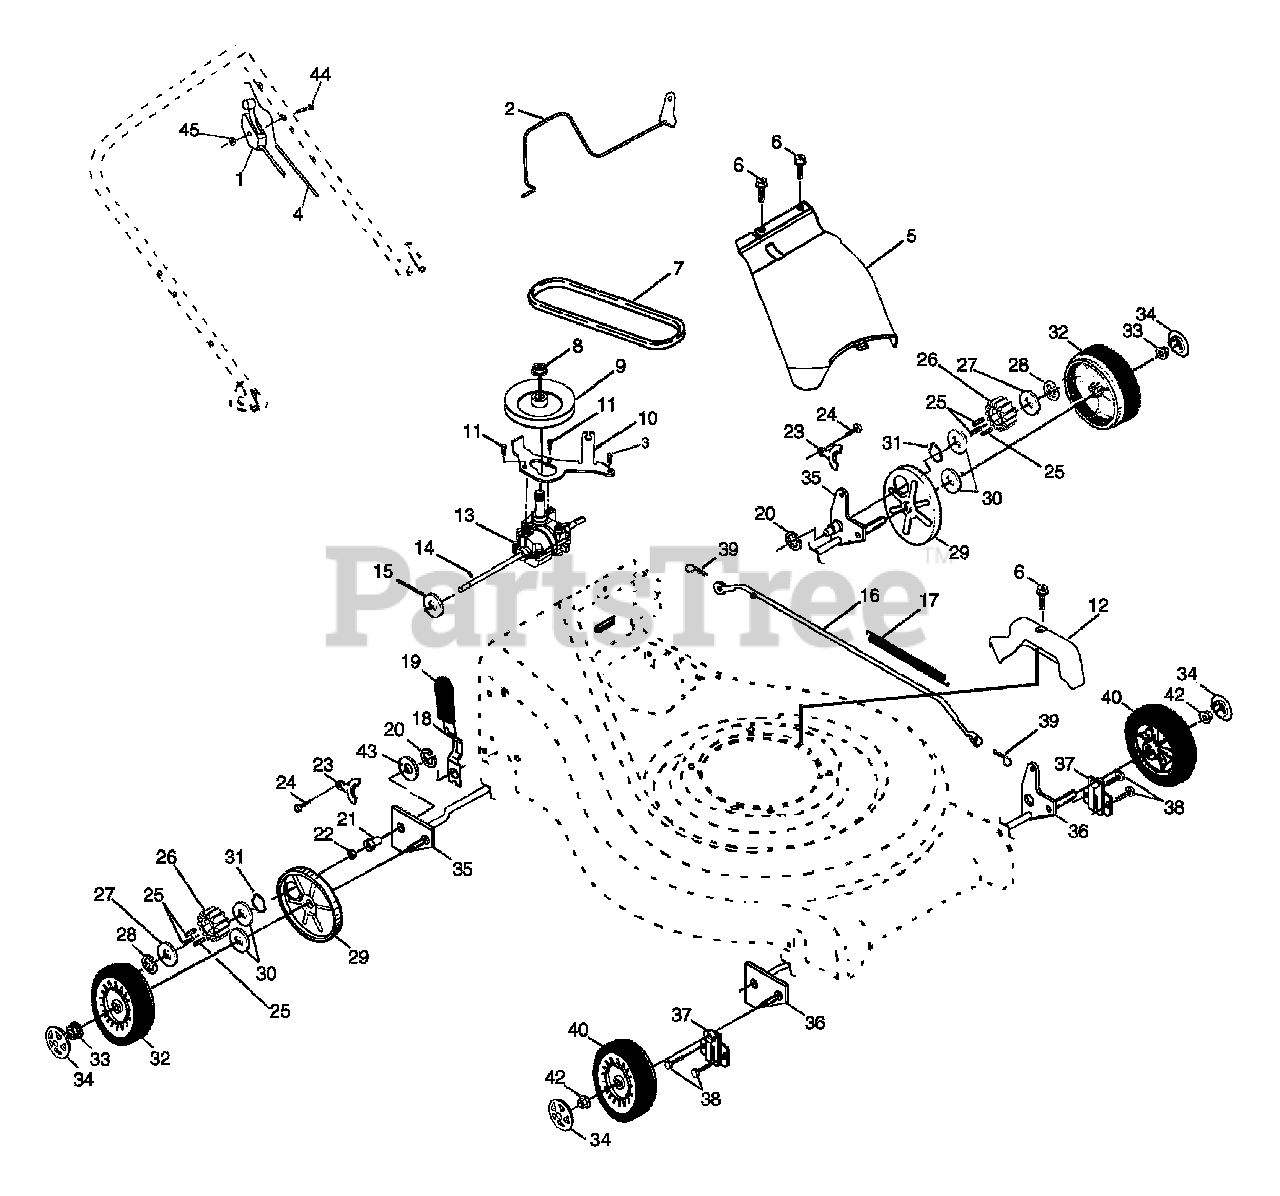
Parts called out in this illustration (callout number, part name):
1	Speed Control
2	Bail Control Drive
4	Drive Cable
5	Cover Drive
6	Screw Thdrol 10-25 x .50
8	Nut Lock Flanged 3/8-16 Zinc
9	Pulley Driven
10	Belt Keeper Bracket
11	Screw Hex Wash Head 10-24 X .668
12	Pivot Rod Cover
13	Transmission Asm.
14	Pin Spring Thrust
15	Washer Hardened
16	Rod Connecting
17	Spring Extension
18	Spring Selector
19	Knob Selector Spring
20	E-Ring 7/8
21	Bearing Support
22	Bearing Ball
23	Retainer Drive Asm. Stmp.
24	Screw Hex Head Tapping 1/4-20 x .75
25	Drive Pawl
26	Pinion, Drive
28	E-Ring 7/16
29	Cover, Dust Wheel
30	Washer 1/2 x 1-1/2 x .134
31	Wave Washer
32	Wheel 9 x 2
33	Nut Hex Flange Lock
35	Shaft Asm. Rear
36	Shaft Asm. Front
37	Retainer Front Shaft
38	Screw 12 x 5/8
39	Clip Retainer
40	Wheel 8 x 2
42	Nut, Hex Flange Lock 3/8-16
44	Screw 1/4 x 2.12
45	Locknut
